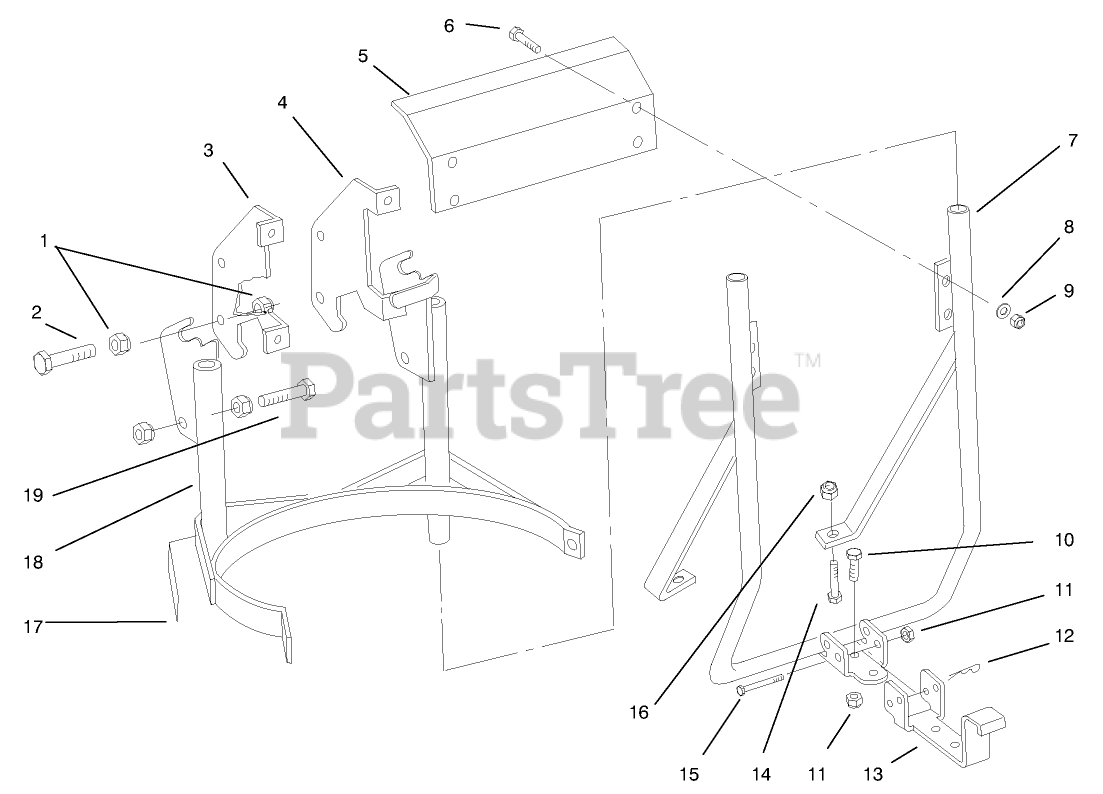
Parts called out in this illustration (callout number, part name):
1	NUT-HEX
2	SCREW-HH
3	LH TOP BRACKET B
4	RH TOP BRACKET B
5	SHIELD-HEAT B
6	SCREW-HH
7	WA - BAGGER MOUNT
8	WASHER-PLAIN
9	NUT-LOCK, NI
10	SCREW-HH
11	NUT-LOCK, NI
12	PIN-COTTER, HAIR
13	BRACKET-SUPT B
14	SCREW-HH
15	SCREW-HH
16	NUT-LOCK, NI
17	DECAL-DANGER
18	WA-CANISTER SUP W/DECALB
19	SCREW-HH
